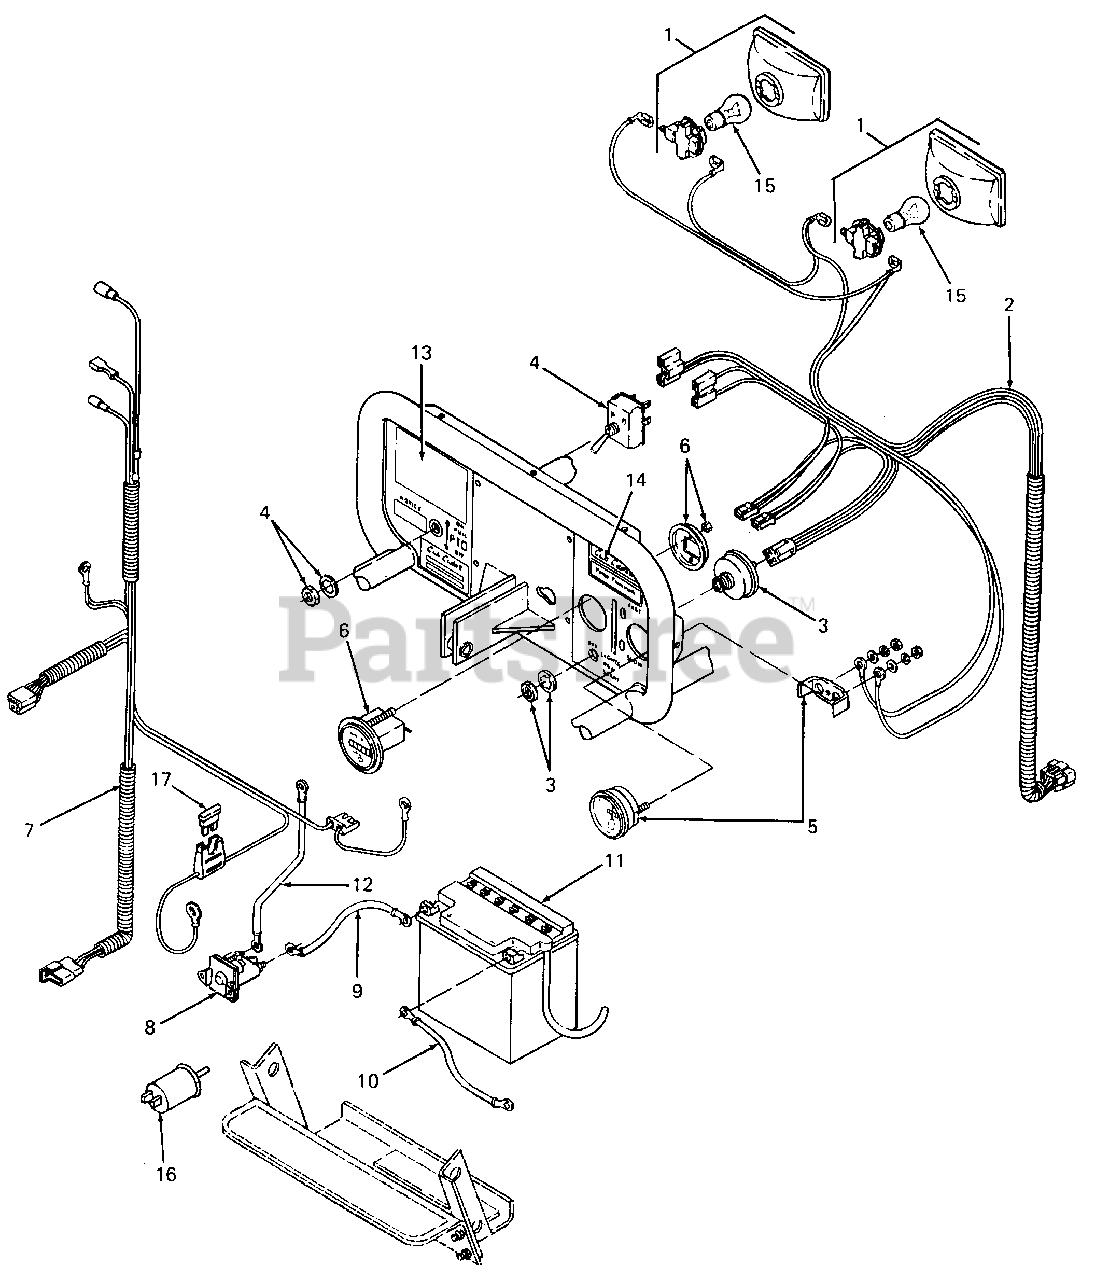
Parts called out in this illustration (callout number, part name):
1	Headlamp Assy
2	Harness, Wire (Upper)
3	Switch, Ignition
4	Switch, Clutch
5	Ammeter
6	Hourmeter
7	Harness, Wire (Lower)
8	Solenoid, Starter
9	Cable, Positive
10	Cable, Ground
11	Battery, 12V
12	Cable, Starter
13	Decal, Caution
14	Decal, Gauge
15	Bulb, 12VGE-1156
16	Switch, Neutral Bypass
17	Fuse, 20 Amp
